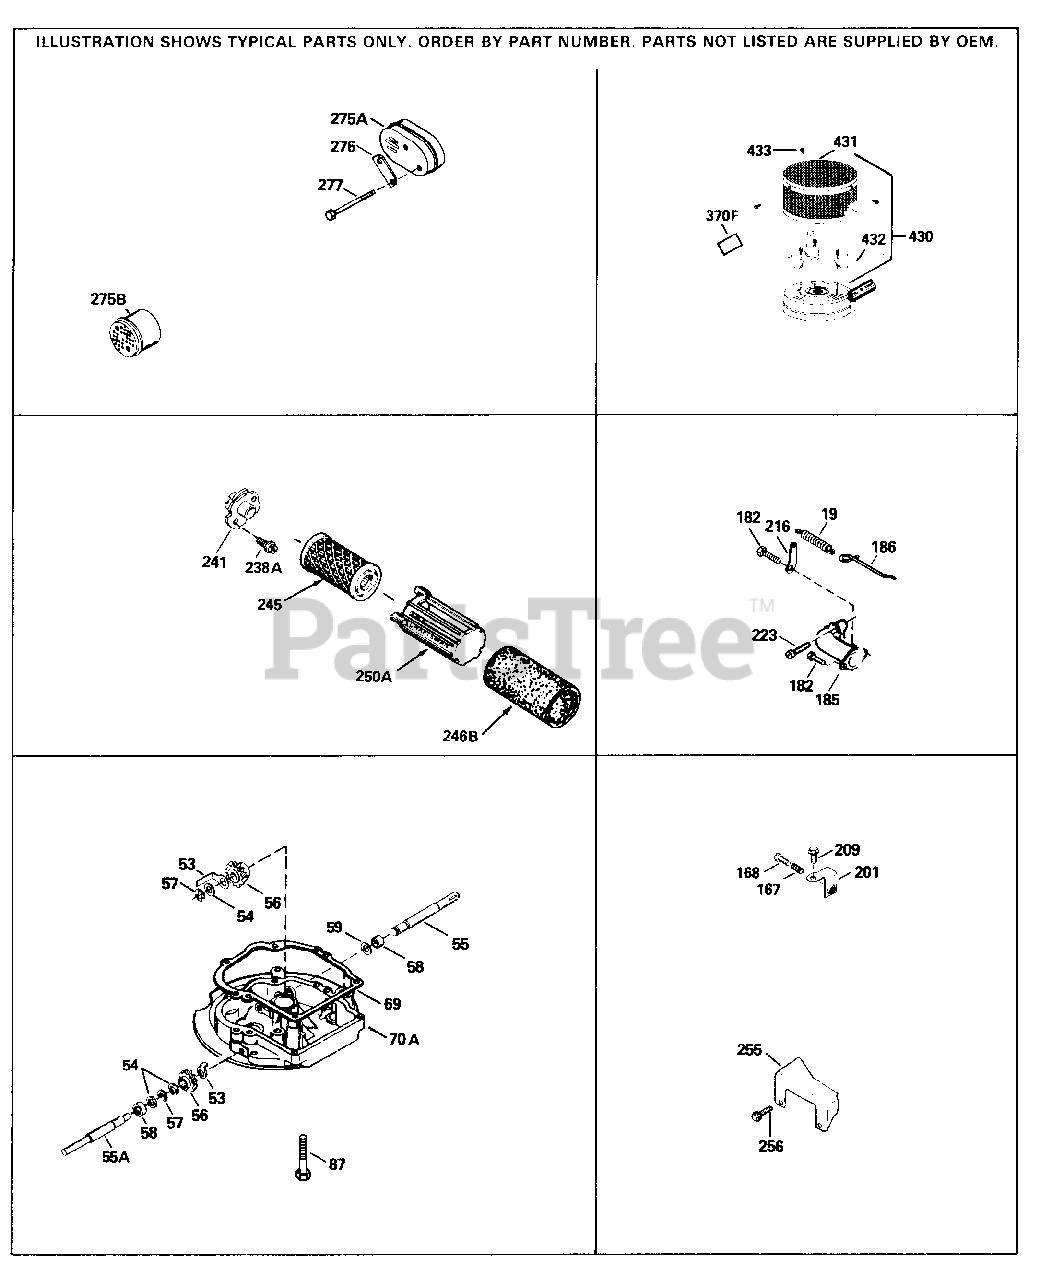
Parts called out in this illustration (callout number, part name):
19	Extension Spring
69	* Mounting Flange Gasket
110A	Ground Wire
179	Retainer Clip
182	Screw, 1/4-28 x 7/8"
185	Intake Pipe (Incl. 224)
186	Governor Link
209	Screw, 10-24 x 9/16"
223	Screw, 1/4-20 x 1"
245	Air Filter (Poly) (also available in Packaged Part #740023B)
275A	Spark Arrestor Muffler (Optional) (In cl. 284,284A,416 & 417)
277	Screw, 1/4-20 x 2-5/16"
284	Muffler Deflector (Incl. 284A)
284A	Screw, 8-32 x 3/8"
324	Terminal
370B	Control Decal
416	Spark Arrestor Kit (Incl. 417) Option al
417	Screw, 8-32 x 3/8" (Optional)
